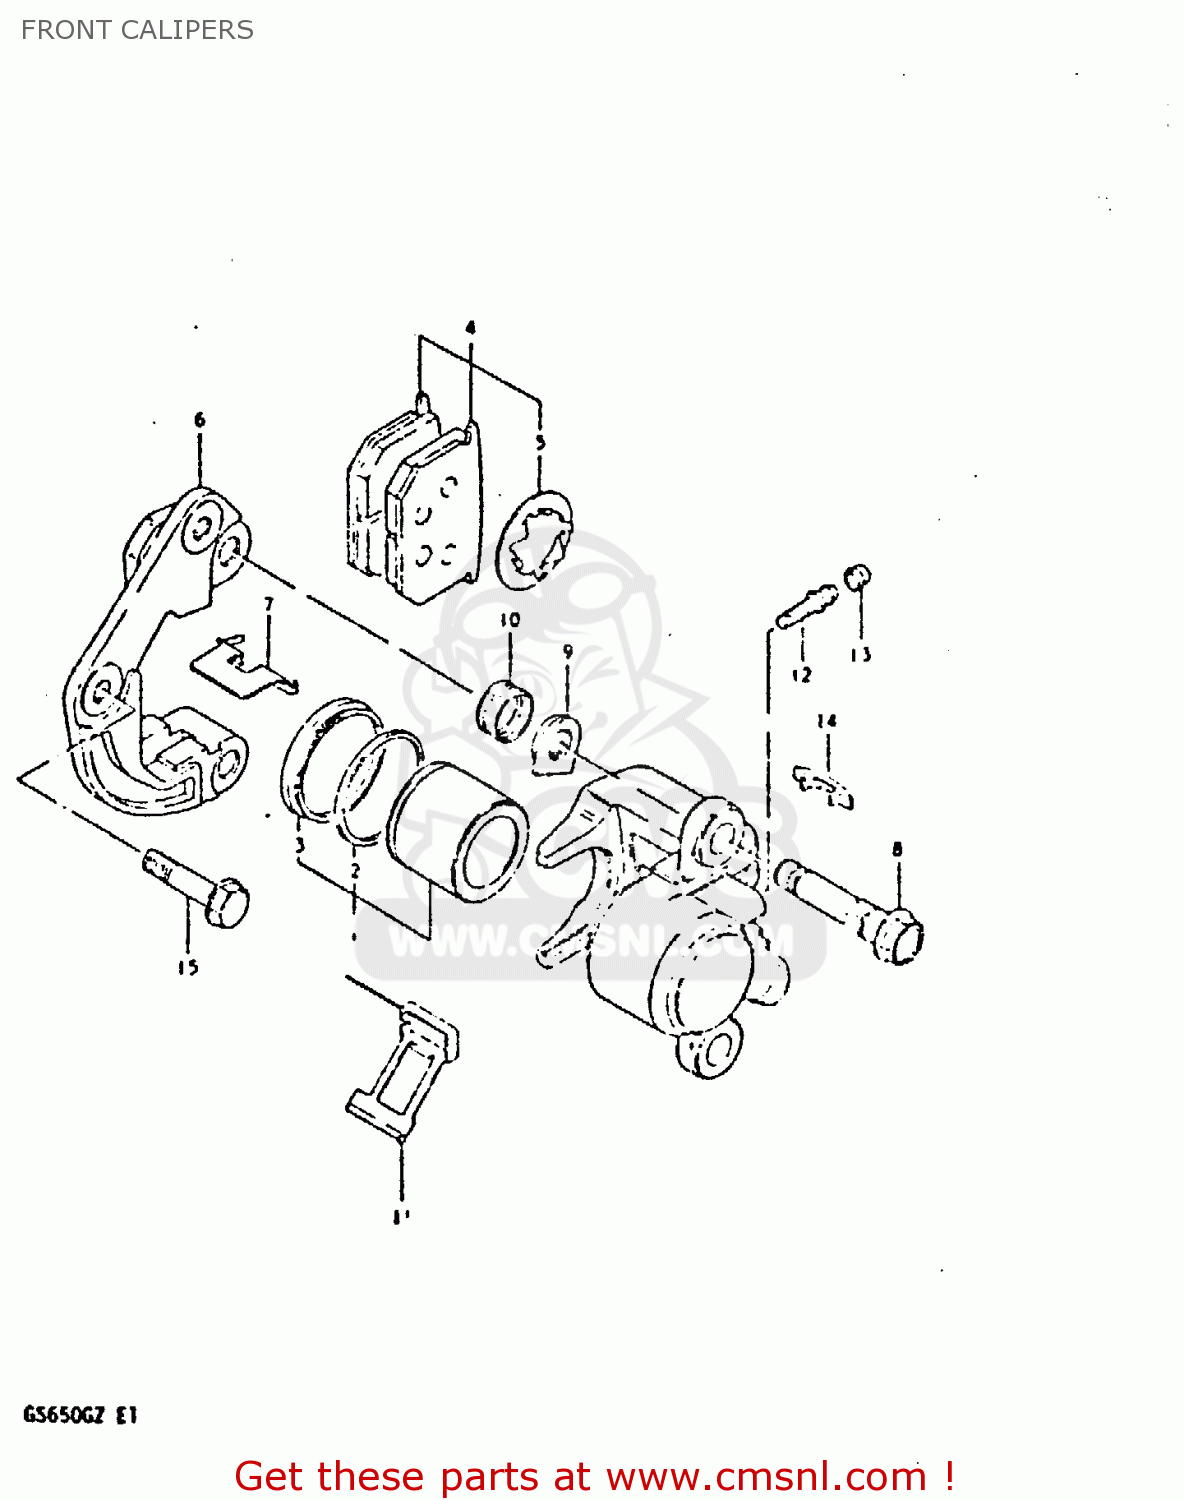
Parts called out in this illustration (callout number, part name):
1	PISTON SET
2	SEAL,PISTON
3	BOOT,PISTON
4	PAD & SHIM SET (MCA)
5	SHIM,PAD
6	HOLDER,CALIPER,LEFT
7	PAD,GUIDE
8	AXLE,CALIPER
9	NUT,CALIPER AXLE
10	BOOT
11	SPRING
12	BREATHER
13	CAP,BLEEDER PL
14	COVER,INDICATOR
15	BOLT 10X37
